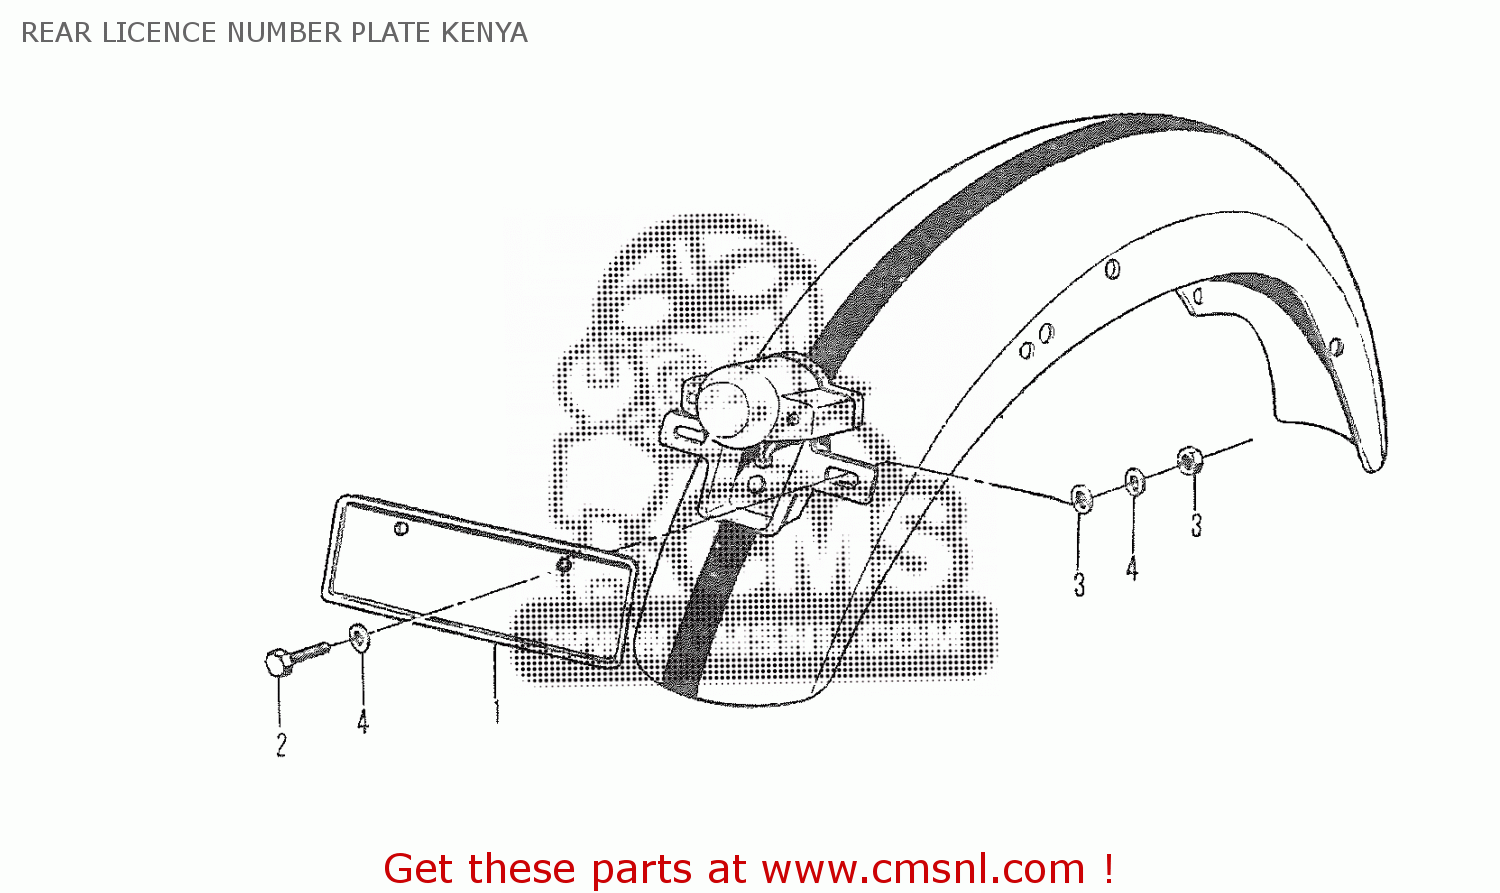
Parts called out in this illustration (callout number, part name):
1	PLATE,RR LICENSE
2	HEXAGON BOLT
3	HEXAGON NUT
4	LOCK WASHER
5	FLAT WASHER
